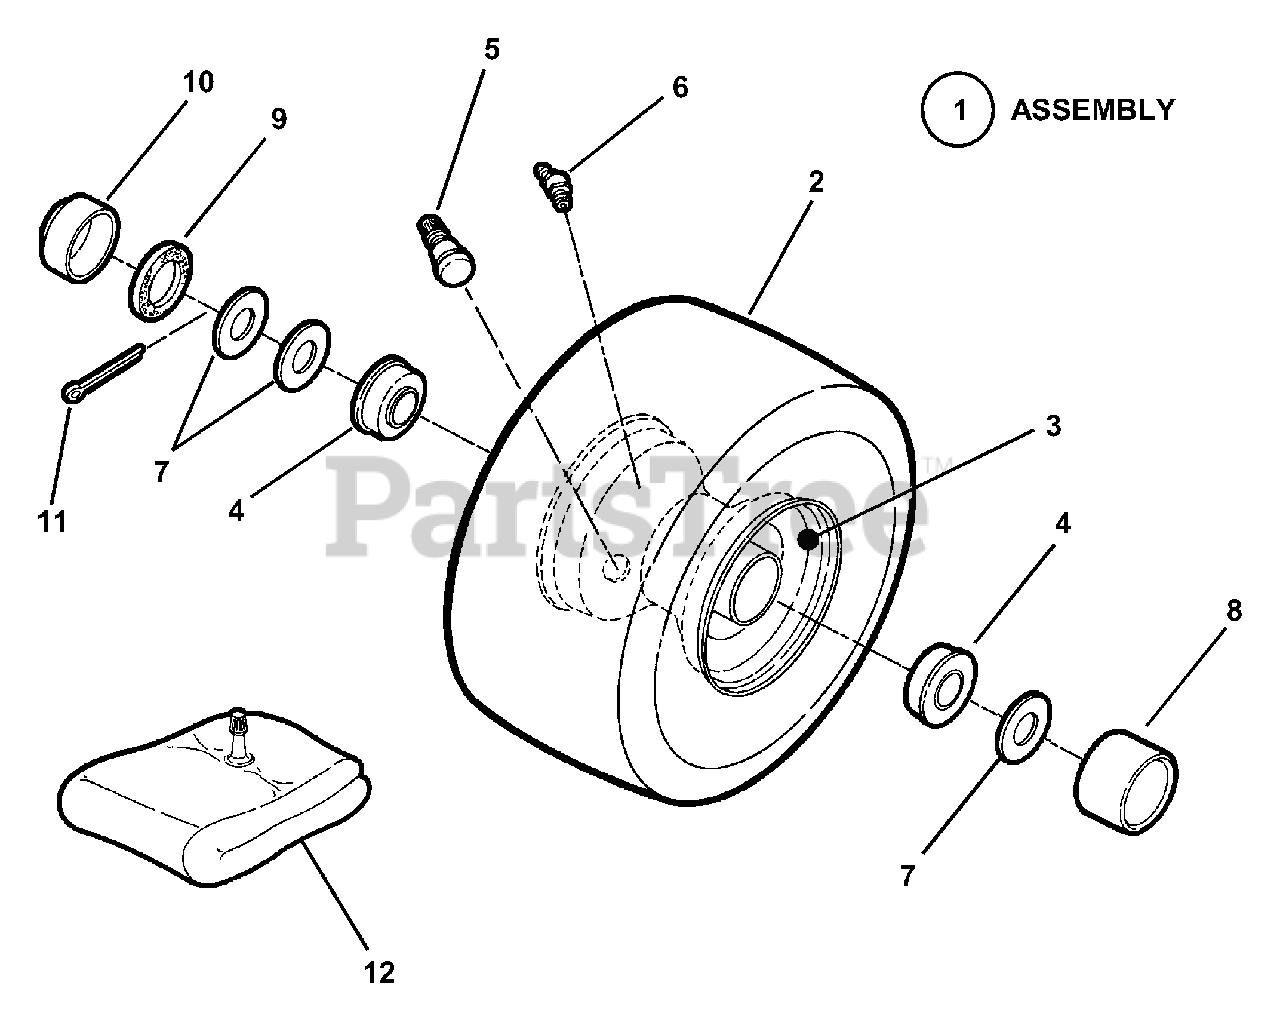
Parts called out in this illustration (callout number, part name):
1	ASSEMBLY, Front Tire & Rim (11.0")
2	TIRE, Pneumatic 11 x 4.00-4 (Kenda)
3	RIM
4	BEARING, Ball
5	VALVE, Air (Snap-In)
6	FITTING Lube
7	WASHER
8	CAP, Hub
9	SEAL, Felt
10	CAP, Dust
11	COTTER-PIN, 5/32 x 1"
12	TUBE, Inner
